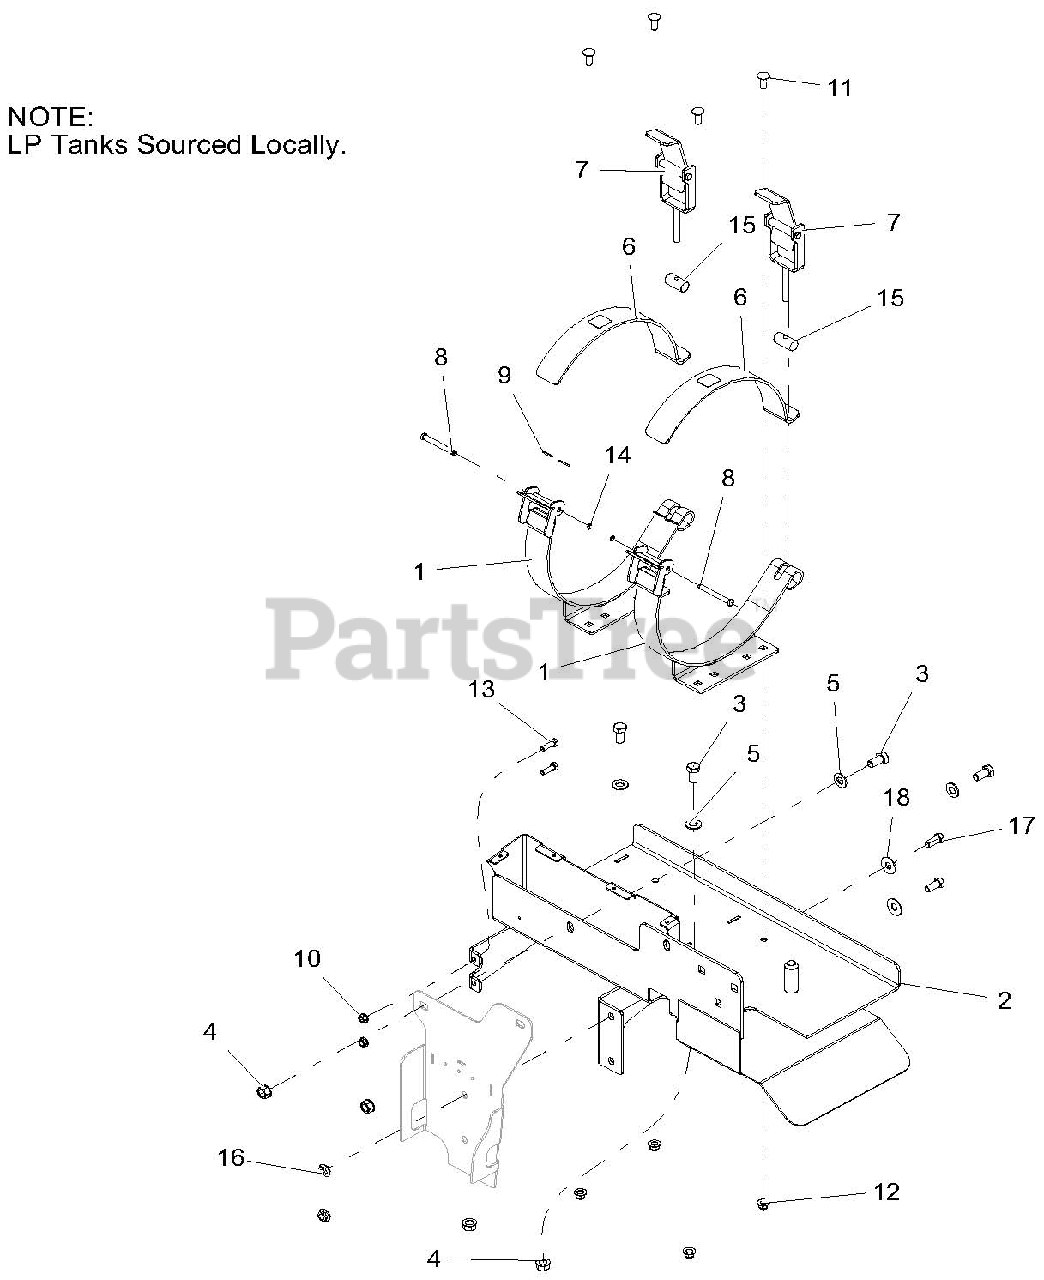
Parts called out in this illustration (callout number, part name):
1	WLDMT, CLAMP LP TANK
2	WLDMT, TANK -LH LP
3	BLT-HEX .50-13X1.00 GR5 YWZC
4	NUT, LK-TOP-FLG .50-13 YWZC
5	WSHR-FL-STL.531X1.06X.095YWZC
6	LP TANK CLAMP W/SAFETY DECAL
7	ASM, LP TANK HANDLE CLAMP
8	PIN, LP CLAMP
9	MAGNET, .75X.060, LP CLAMP
10	NUT, LK-TOP-FLG .312-18 YWZC
11	BLT-RDHDSQNK .38-16X1.00 G5 YWZC
12	NUT-LK-NYL-FLG .38-16 YWZC
13	BLT-HEX .31-18X1.00 GR5 YWZC
14	RG-RTNG-EXT .312X.025
15	PIVOT, LP CLAMP HANDLE
16	NUT-LK-NYL-FLG .44-14 YWZC
17	BLT-HEX .44-14X1.00 GR5 YWZC
18	WSHR-FL-STL..50X1.25X.083 YWZ
